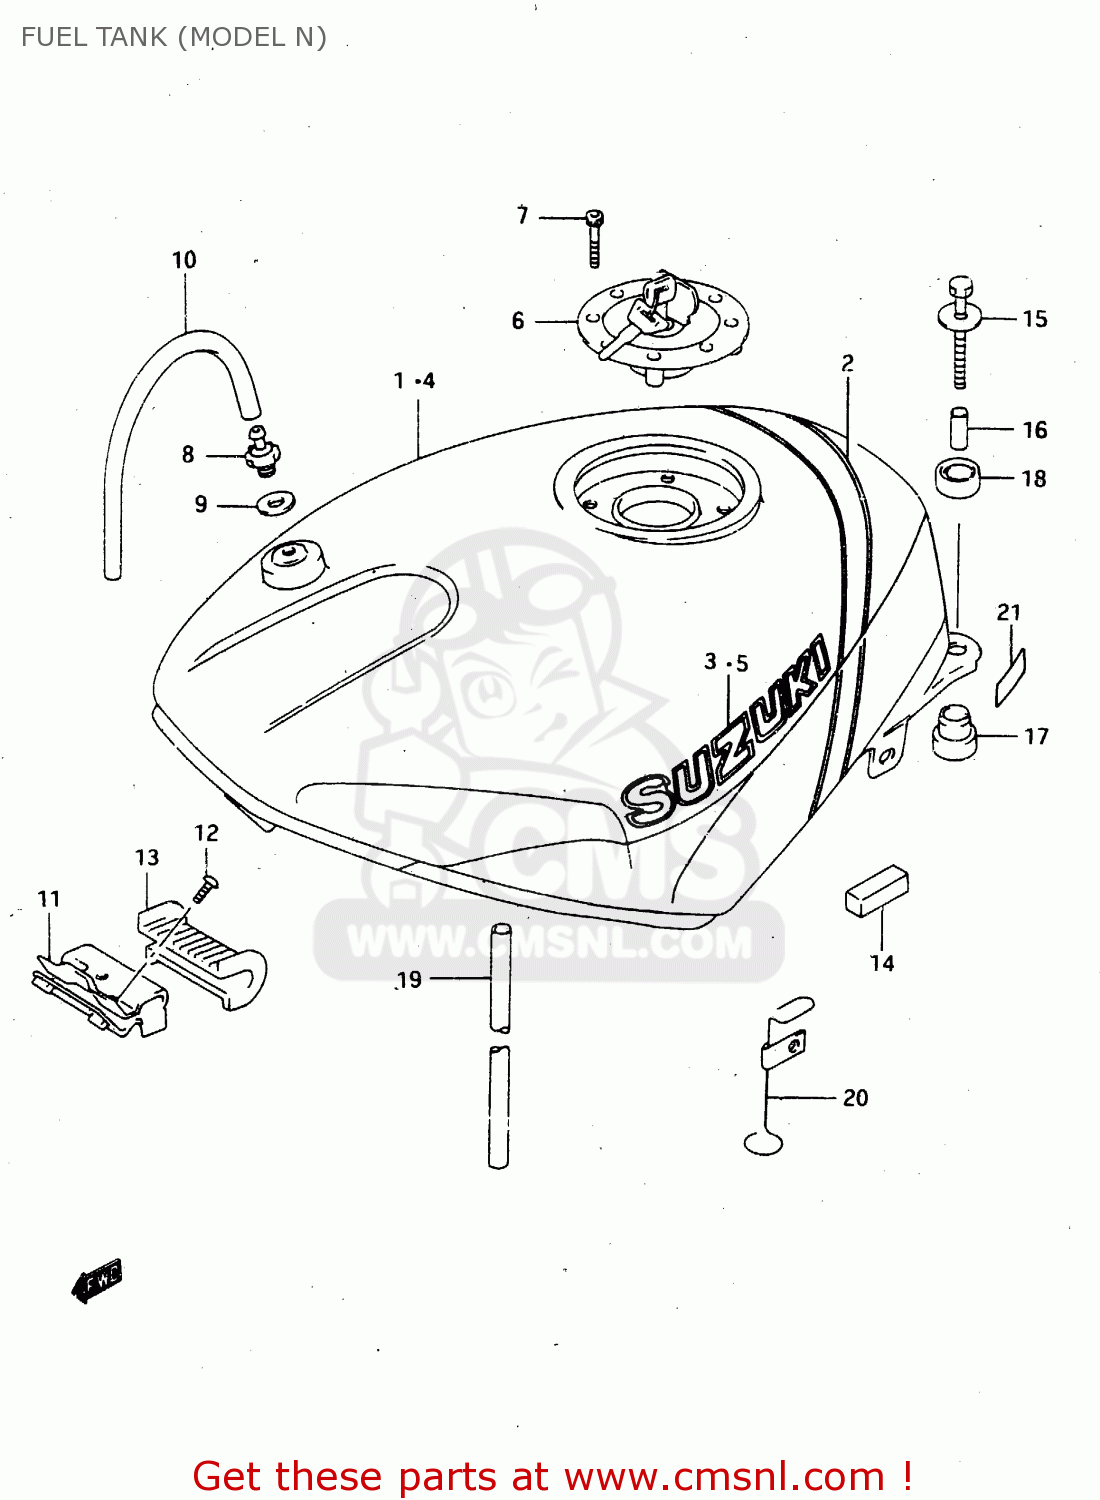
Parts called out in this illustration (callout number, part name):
1	TANK ASSY, FUEL
2	TAPE, FUEL TANK
3	EMBLEM,FUEL TANK(WHITE)
4	TANK ASSY, FUEL (BLACK)
5	EMBLEM
6	CAP SET,FUEL TANK
7	BOLT(5X20)
8	PLUG,FUEL TANK BREATHER
9	GASKET(12.5X20X2.5) (NAS)
10	HOSE(5X8.2X600)
11	BRACKET,FUEL TANK
12	SCREW
13	CUSHION,FUEL TANK,FRONT
14	CUSHION,FUEL TANK SIDE
15	BOLT
16	SPACER
17	CUSHION
18	CUSHION
19	HOSE(5X8.2X2000)
20	GUIDE, DRAIN HOSE
21	PROTECTOR,FRAME COVER NO.2
